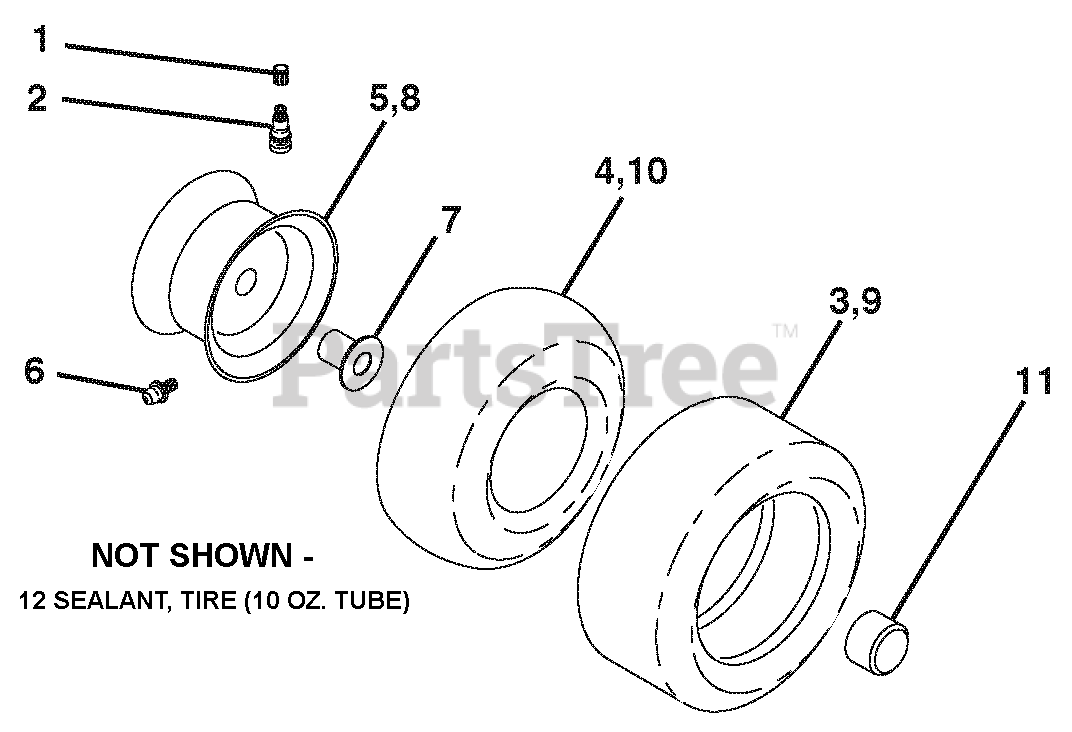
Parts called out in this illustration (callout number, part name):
1	CAP.VALVE.TIRE
2	STEM.VALVE
3	TIRE.F.TS.15 X 6.0 - 6.SERVICE
4	TUBE.INNER.FRONT.#35060
5	RIM ASM.6"FRONT.BLACK.SERVICE
6	FITTING.GREASE
7	BEARING.FLANGE
8	RIM ASM.8"REAR.BKACK.SERVICE
9	TIRE.R.TS-LT.18X9.5-8.C.SERV.
10	TUBE.REAR.9.5 X 8.SERVICE
11	CAP.HUB.AXLE.BLK.1.50 X 1.00
